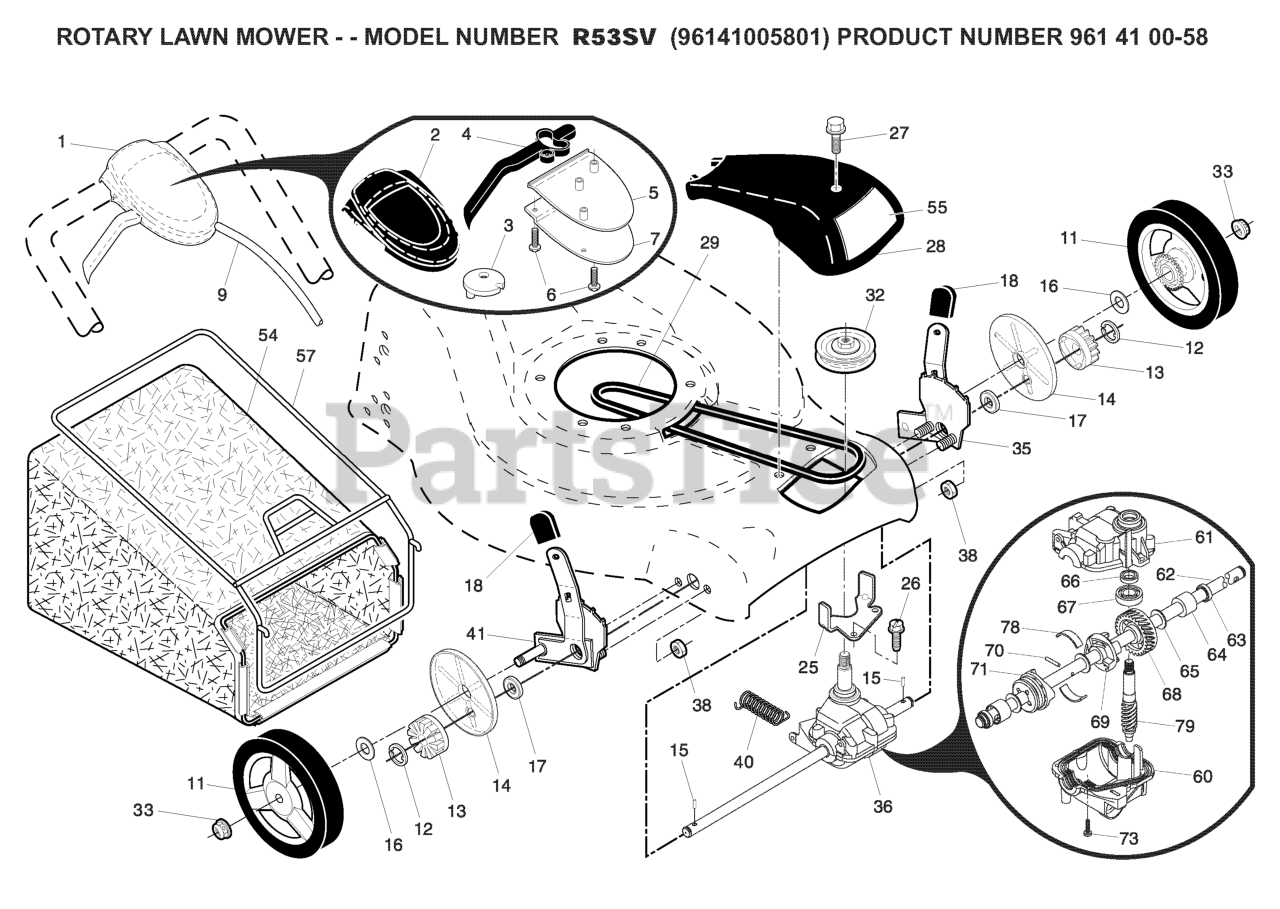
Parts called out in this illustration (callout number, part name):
1	DRIVE CONTROL ASSEMBLY (INCLUD
2	COVER TOP AUTO WALK CONTROL
3	PULLEY.CAM.DRIVE.CONTROL.EZ
4	LEVER, AUTOWALK DRIVE CONTROL
5	COVER BOTTOM AUTO WLK CONTROL
6	SCREW, PHILLIPS HEAD 10 X 5/8
7	BRACKET.DRIVE.CONTROL.MOUNT.BL
9	CABLE ASSEMBLY, DRIVE
11	WHEEL.8X1.75.H3SPK.RAD3.GY.BU3
12	E-RING 7/16 RE
13	PINION.14.TEETH.FGD
14	COVER.DUST.WHEEL
15	PAWL, DRIVE
16	WASHER FLUT
17	BEARING
18	SELECTOR KNOB
25	BELT KEEPER
27	SCREW, HEX HD TAPPING #10-24 1
28	COVER.DRIVE.21.FWGD.GRAY
29	BELT.DRIVE.FG
32	RP PULLEY.DRIVE.EZ
33	NUT.HEX.FLANGE.3/8-16.LO(3 2)
35	WHEEL ADJ KIT LH
36	TRANSMISSION.21.FGD.HT.VST
38	LOCKNUT.NYLOC.1/4-20
41	Manual, Owner's
54	Grassbag Assembly
55	DECAL DRIVE COVER
57	FRAME.GBAG.21.FWGD
61	CASE.UPPER.00254(SERVICE)
62	SHAFT OUTPUT (12289)
63	SEAL.OUTPUT.SHAFT
66	SEAL INPUT SHAFT
68	GEAR 28 TEETH 36208
69	FIXED DOG CLUTCH
70	PIN.3.50.33733
71	MOVEABLE DOG CLUTCH
74	CASE.BOTTOM.
78	SPRING LEAF
79	SHAFT WORM
